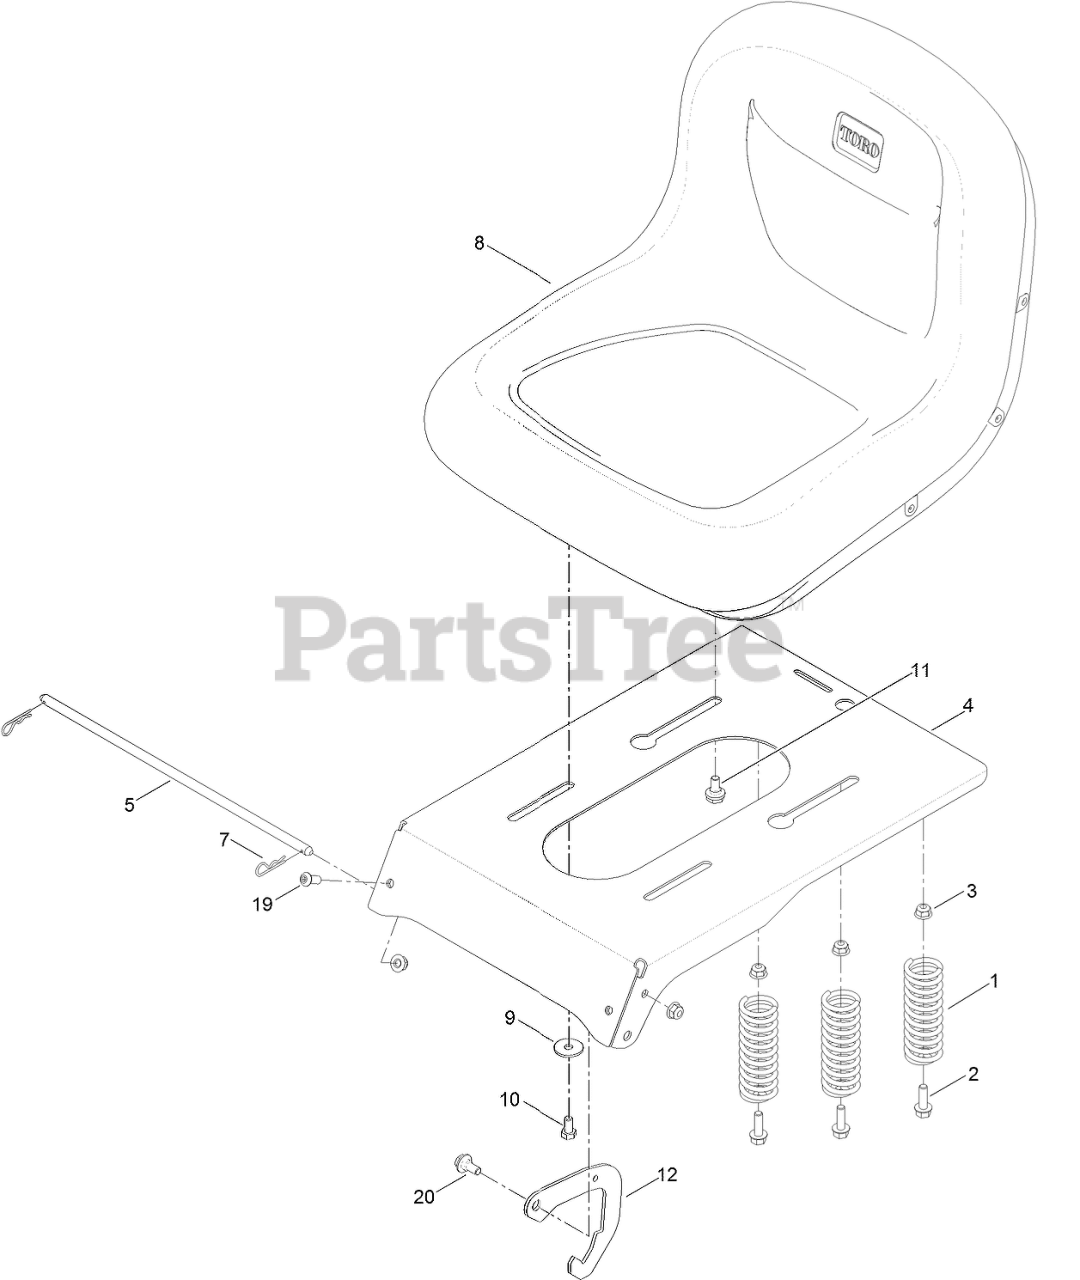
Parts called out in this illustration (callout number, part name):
1	SPRING-COMPRESSION
2	SCREW-HHF
3	NUT-HF, NI
4	PAN-SEAT
5	ROD-PIVOT, NARROW
7	PIN-COTTER
8	SEAT-15 INCH
9	WASHER-PIVOT
10	SCREW-HH
11	BOLT-SHOULDER,HFH
12	LATCH-SEAT
19	SCREW-HSBH
20	SCREW-SHOULDER
